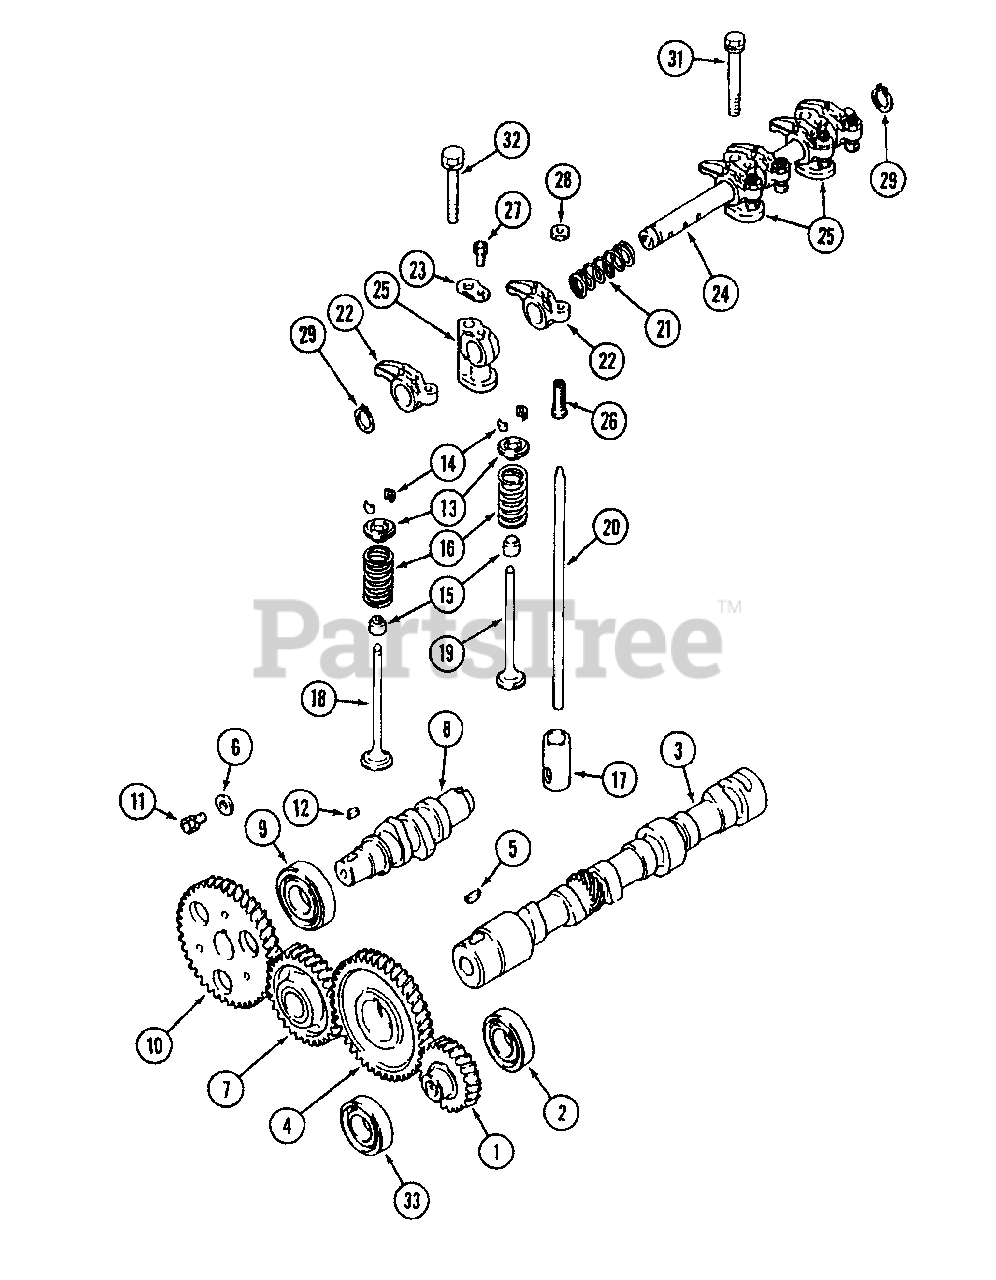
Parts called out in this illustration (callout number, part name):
1	Gear, Pressure Oil Pump
2	Bearing, Ball
4	Gear, Camshaft
5	Key, Woodruff
7	Gear Ass'y., Idler
8	Shaft, Fuel Injection Pump
9	Bearing, Ball
10	Gear, Fuel Injection Pump
11	Bolt, w/Washer
13	Retainer, Valve Spring
14	Retainer Lock, Valve Spring
15	Seal, Valve Stem
17	Tappet
18	Valve, Intake
19	Valve, Exhaust
21	Spring, Rocker Shaft LH
22	Arm, Rocker
24	Shaft Ass'y., Rocker
25	Stay, Rocker
26	Screw, Adjusting
27	Bolt, w/Washer
28	Nut, Jam
31	Bolt, w/Washer
32	Bolt, w/Washer
33	Bearing, Rear
